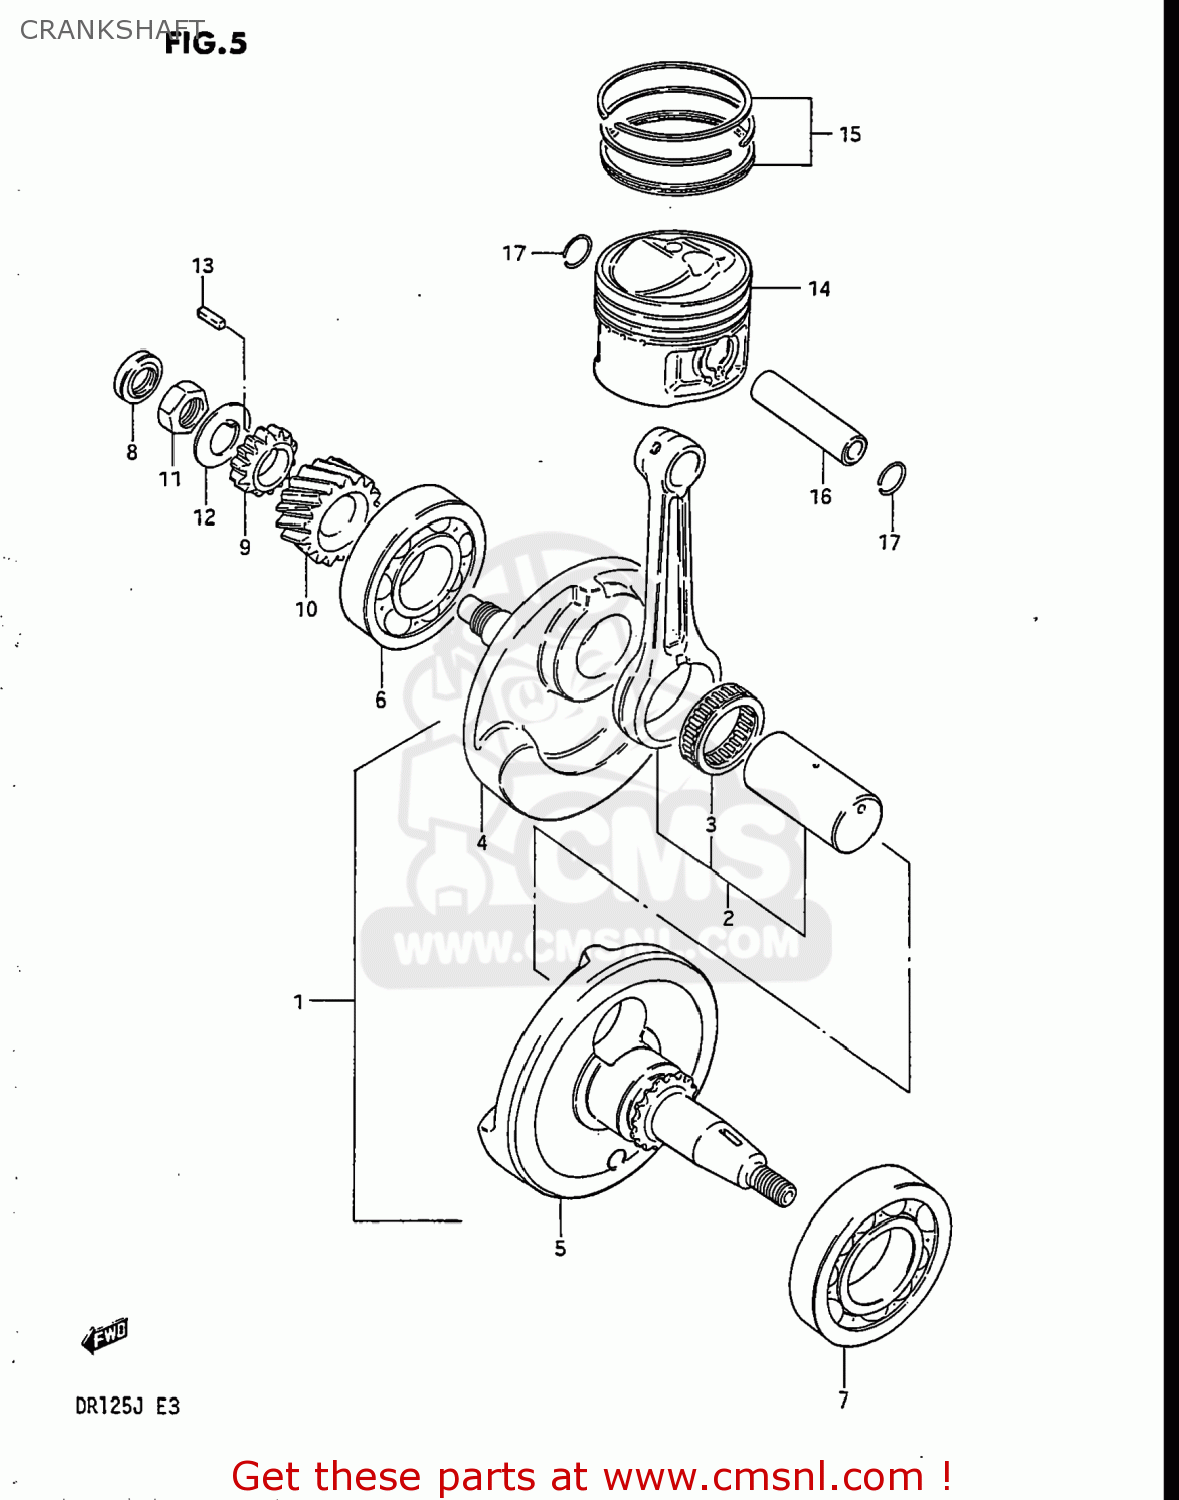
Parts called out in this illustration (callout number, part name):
1	CRANKSHAFT ASSEMBLY
2	CRANKSHAFT ASSEMBLY
3	BEARING
4	CRANKSHAFT
5	CRANKSHAFT,LEFT
6	BEARING(28X68X18)
7	BEARING
8	OIL SEAL
9	GEAR,OIL PUMP DRIVE
10	GEAR,PRIMARY DRIVE
11	NUT
12	WASHER
13	KEY
14	PISTON (STD)
15	RING SET,PISTON
16	PIN,PISTON
17	RING,SNAP 14MM
